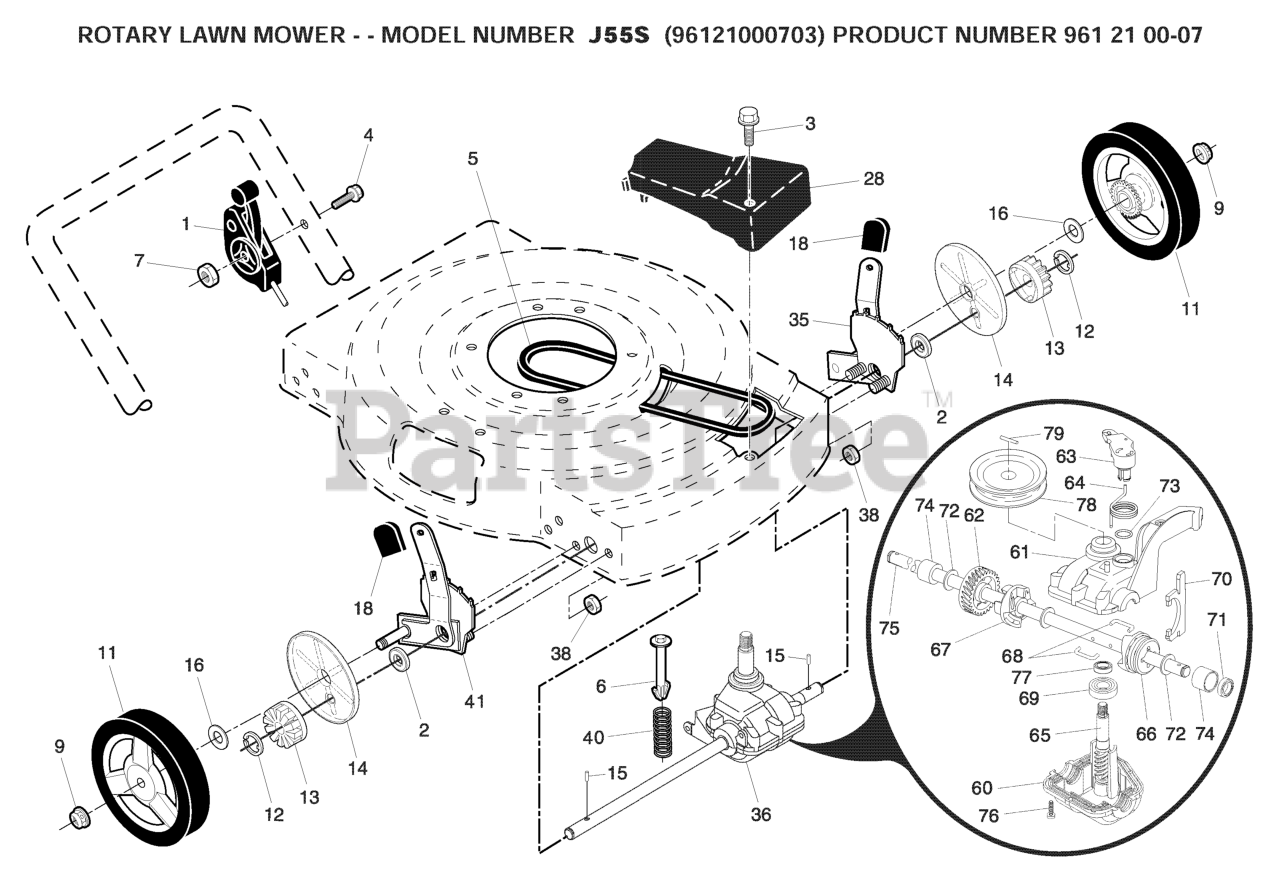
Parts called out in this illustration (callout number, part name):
1	DRIVE CONTROL 59.8 FWGD
2	BEARING
3	Screw, Tapping, Pan Head #10-24 x 2-3/4
4	SCREW.PAN.HEAD
5	BELT THERM .32
6	SPRING RETAINER
7	NUT.HEX.FLANGE.1/4
9	NUT.HEX.FLANGE.3/8-16.LO(3 2)
11	WHEEL.8X1.75.H3SPK.RAD3.GY.BU3
12	E-RING 7/16 RE
13	PINION.14.TEETH.FGD
14	COVER.DUST.WHEEL
15	PAWL.DRIVE
16	WASHER FLUT
18	SELECTOR KNOB
28	Drive Cover
35	KIT WHEEL ADJUSTER LH
36	TRANSMISSION.22.FGD.W/PULLEY
38	LOCKNUT.NYLOC.1/4-20
40	SPRING.EXTENSION
41	KIT WHEEL ADJUSTER RH
60	LOWER CASE
61	UPPER CASE
62	GEAR.27.TEETH.WALK.MOWER
63	LEVER, CLUTCH
64	SPRING, RETURN
65	SHAFT INPUT (13041)
66	DOG, MOVABLE (11032)
67	DOG, FIXED GT11031
68	WIRE, FORMED (15966)
70	FORK, SHIFT
71	SEAL.OUTPUT.SHAFT
73	SEAL, CASE O-RING
75	SHAFT OUTPUT (12260 NOW 12663)
77	SEAL INPUT SHAFT
78	PULLEY.DRIVEN.FGD
79	PIN RETAINER
